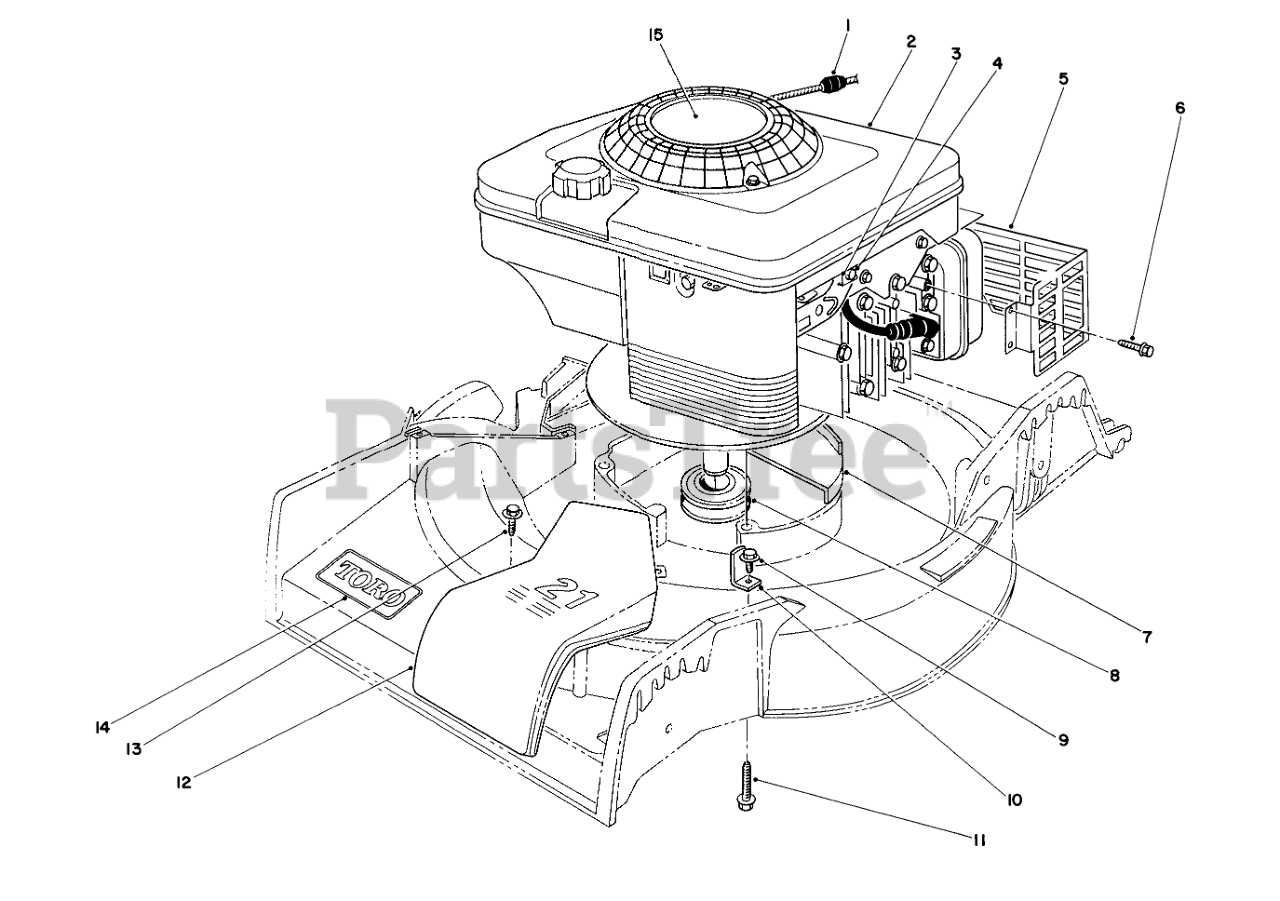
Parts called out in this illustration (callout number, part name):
1	STOP-ROPE
3	CLAMP-CASING
4	CLAMP SCREW F/W ENGINE
5	SHIELD-MUFFLER
6	SCREW-HWH
7	HOUSING CAP
8	PULLEY-DRIVER
9	SCREW-HWHTF
10	BELT GUIDE
11	THD FORM SCREW
12	BELT COVER 21" S D
13	SCREW-HWH
14	DECAL
15	DECAL-ENGINE F/W ENGINE
